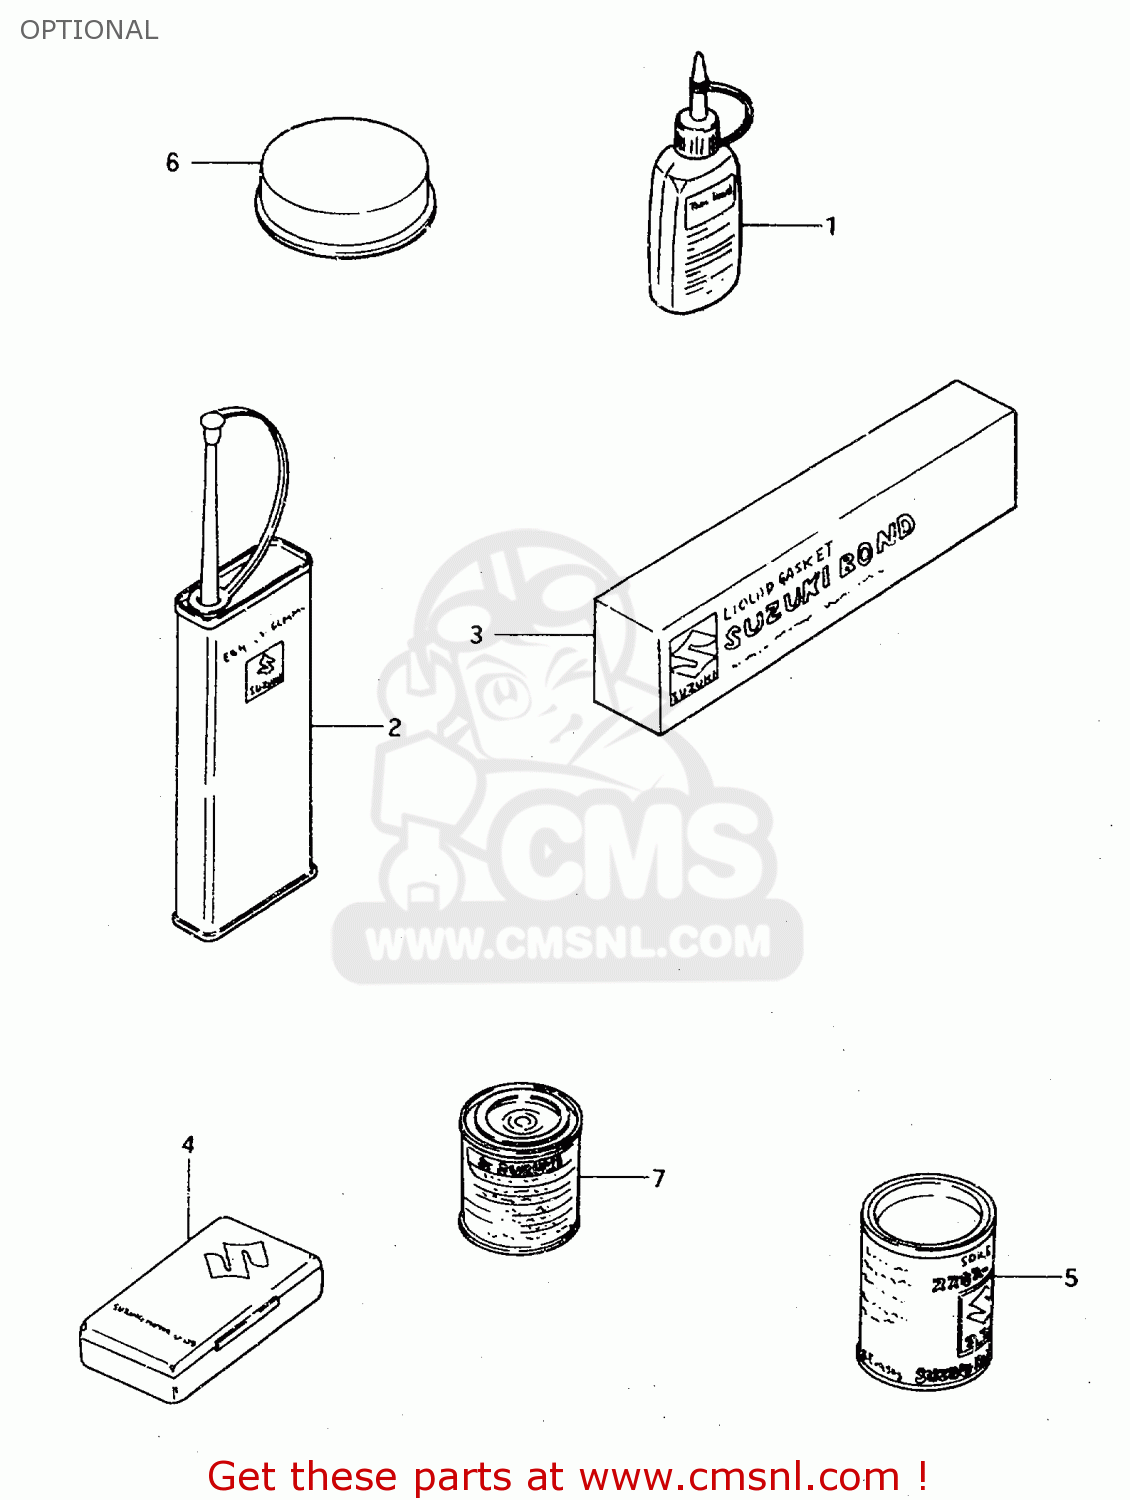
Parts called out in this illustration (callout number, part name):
1	THREAD LOCK NO
2	THREAD LOCK NO.1401 CLEAR 200G
3	BOND 1104
4	TUBE REPARING TOOL
5	GREASE(C)EP2 LITHIUM 150G
6	GREASE,PBC FOR BRK PAD 20G
7	PAINT (SPECIAL WHITE)
